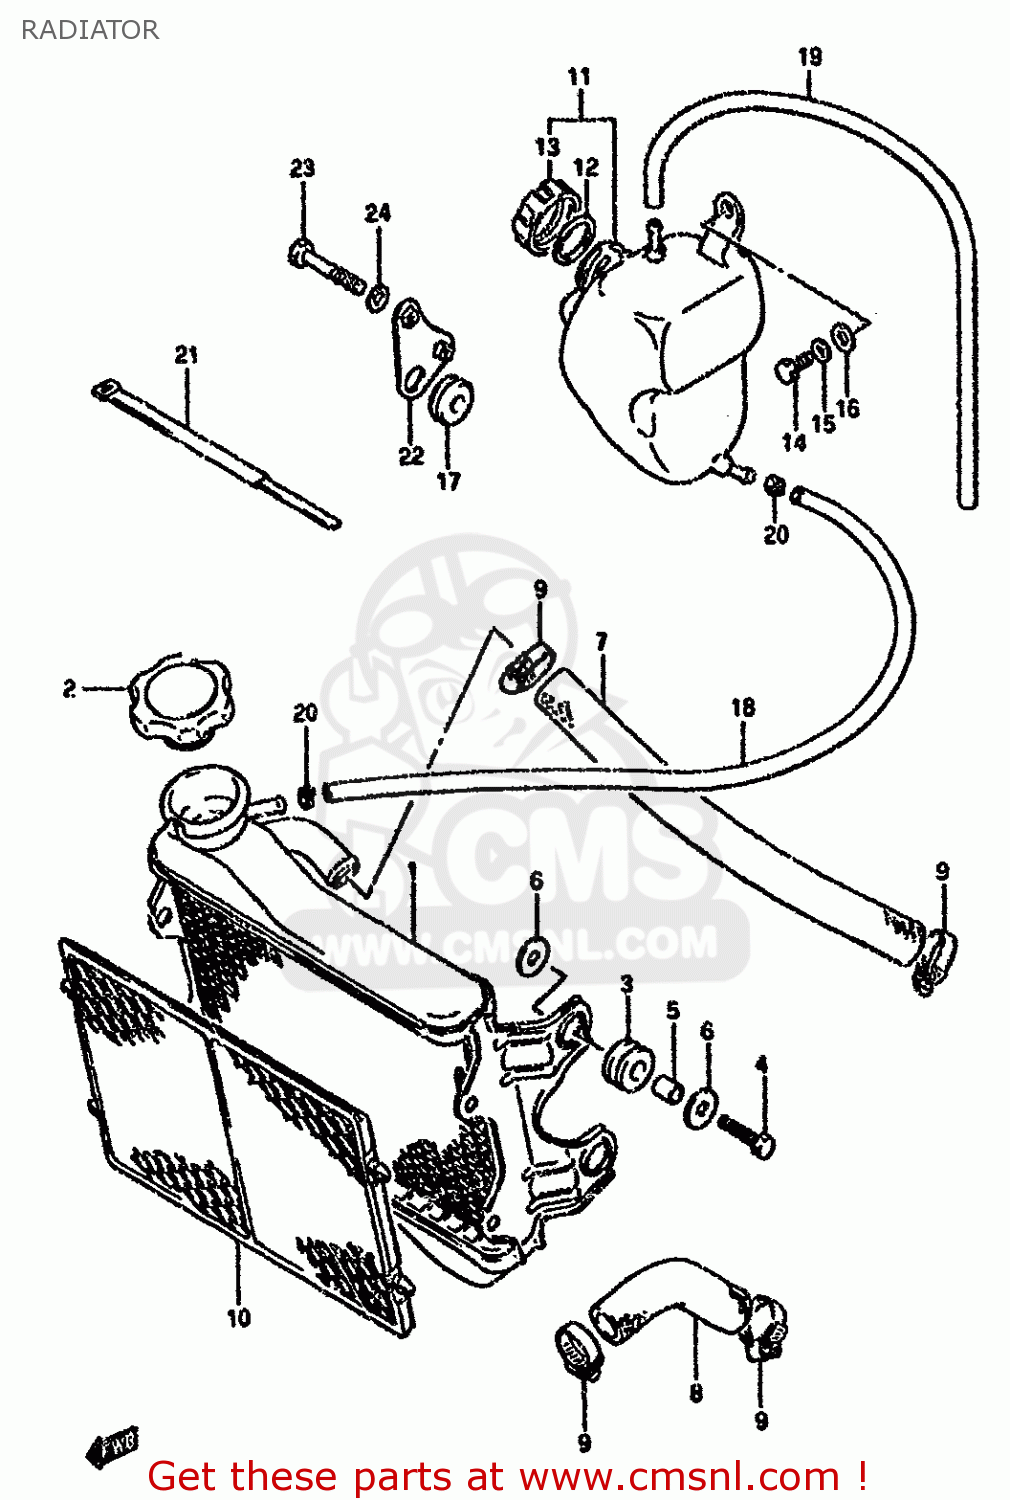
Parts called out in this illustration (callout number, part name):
1	RADIATOR
2	CAP COMP,RADIATOR 1.1
3	CUSHION,RADIATOR LWR
4	BOLT
5	SPACER (7X10X12)
6	WASHER (6.5X22X1.6)
7	HOSE,RADIATOR INLET
8	HOSE,RADIATOR,OUTLET
9	CLAMP
10	NET,RADIATOR
11	TANK ASSY,RESERVOIR
12	GASKET,RESERVOIR TANK CAP (NAS)
13	CAP,RESERVOIR TANK
14	BOLT
15	WASHER,LOCK
16	WASHER (6.5X20X1.2)
17	CUSHION
18	HOSE(5X9X2000)
19	HOSE(5X9X2000)
20	CLIP
21	CLAMP
22	PLATE,RESERVOIR
23	BOLT
24	WASHER,LOCK
